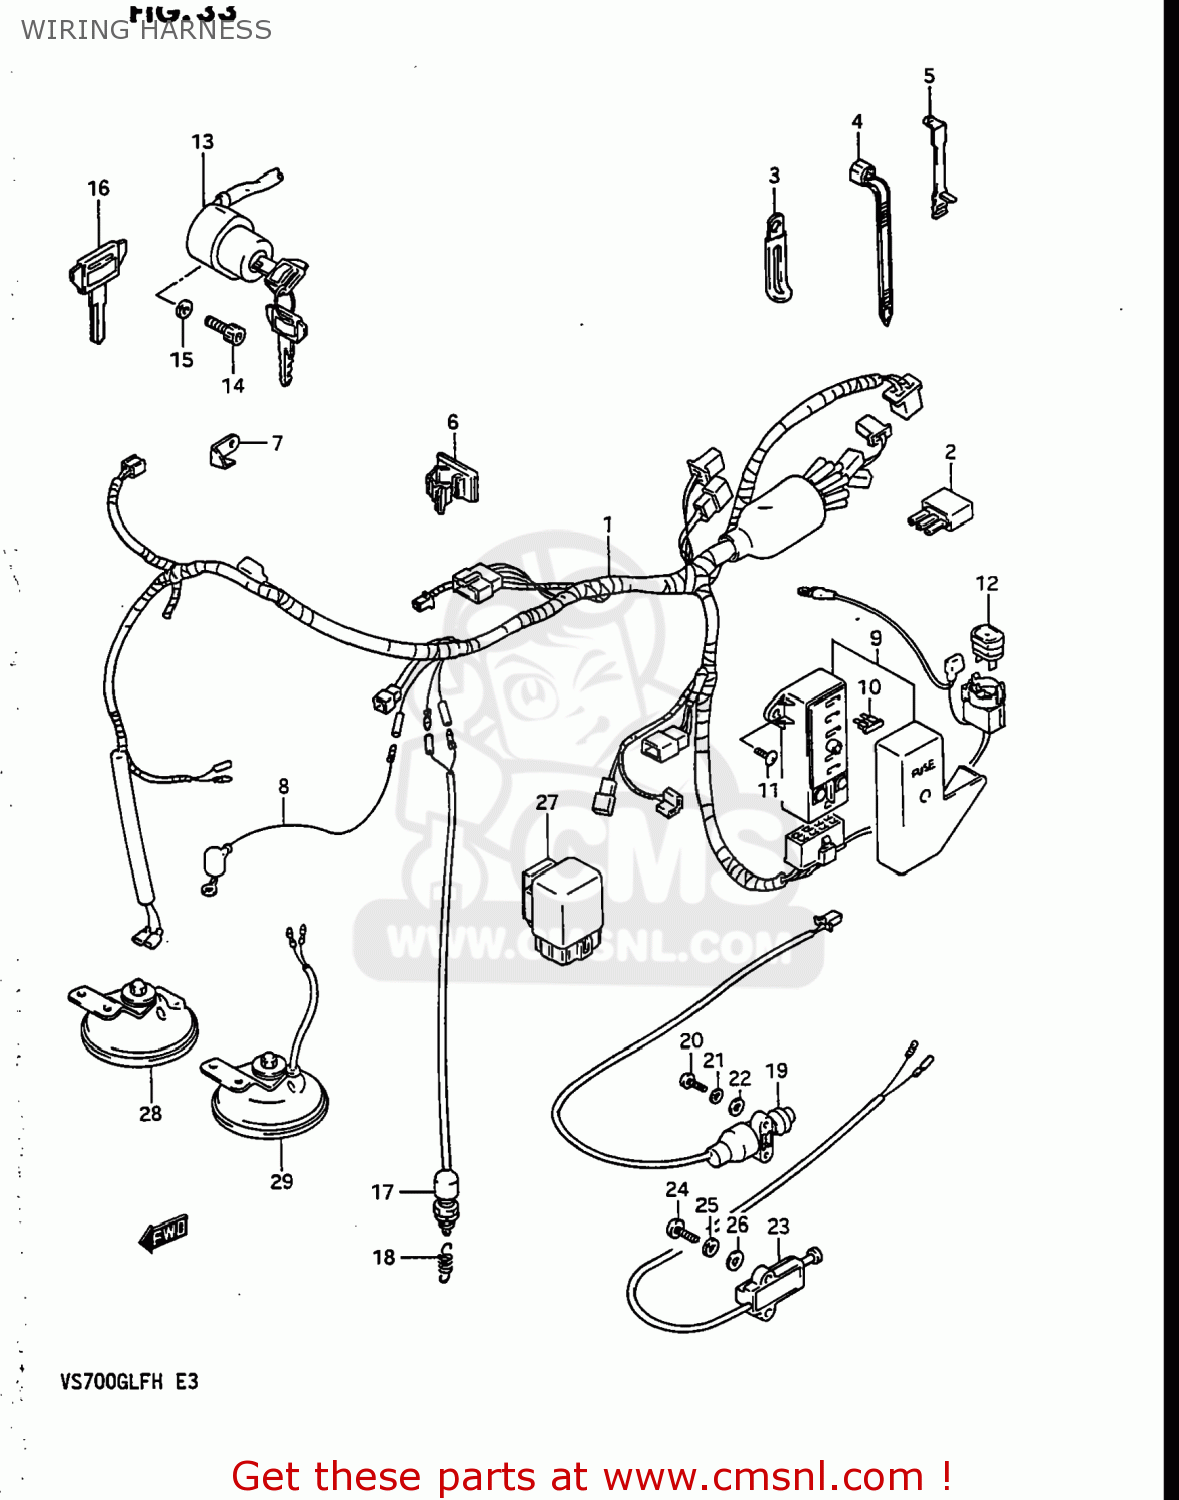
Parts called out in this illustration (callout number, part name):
1	HARNESS,WIRING
2	DIODE(STANLEY DE8804)
3	CLAMP
4	CLAMP(L:95)
5	CLAMP(L:55)
6	CLAMP
7	PLATE,COUPLER HOLDER
8	WIRE,WATER TEMPERATURE GAUGE
9	BOX ASSY,FUSE
10	FUSE(10A)
11	SCREW
12	BREAKER ASSY,CIRCUT
13	SWITCH ASSEMBLY,IGNITION
14	BOLT
15	LOCK WASHER
16	KEY,BLANK(TYPE:C)
17	SWITCH ASSY,STOP LAMP
18	SPRING
19	SWITCH ASSEMBLY,SIDE STAND
20	SCREW
21	WASHER,LOCK
22	WASHER,5MM
23	SWITCH ASSEMBLY,SIDE STAND
24	SCREW
25	WASHER,LOCK
26	WASHER
27	RELAY ASSEMBLY
28	HORN ASSEMBLY
29	HORN ASSEMBLY
